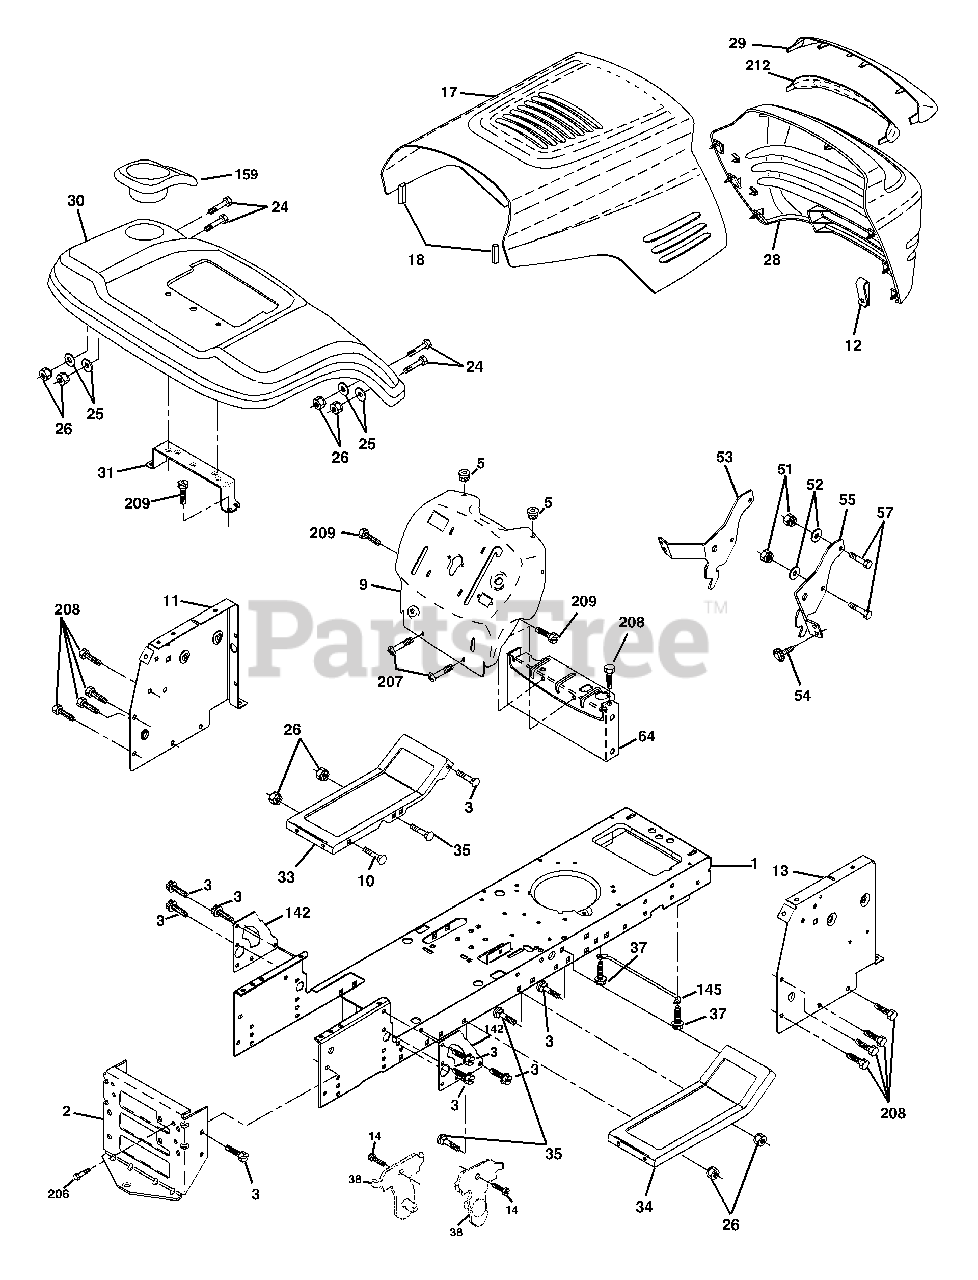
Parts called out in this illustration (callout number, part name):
1	Chassis
2	Drawbar
3	Screw 3/8-16x.75
5	Bumper Hood/Dash
10	Bolt Carriage 3/8-16 x 1
11	Panel Dash Lh
12	Clip Tinnerman
13	Panel Dash Rh
14	Screw Thdrol 3/8-16 x 1-1/4
17	Hood W/Side Louvers
18	Bumper Hood Large
24	Bolt Fin Hex 3/8-16 x 1 Gr 5
25	Washer 13/32 X 13/16 X 12 Ga
26	Nut Lock Hex W/Ins 3/8-16 Unc
29	Lens
30	Fender Footrest STLT Pnt
31	Bracket Support Fender
33	Footrest Pnt Lh
34	Footrest Pnt Rh
35	Bolt Rdhd Sht Sqnk 3/8-16 x 3/4
37	Screw Thdrol 6/16-18 x 1/2 TYT
38	Bracket Asm. Pivot Mower Rear
51	Nut Lock Hex W/Ins 1/4-20
52	Washer 9/32 x 7/8 x 16 Ga.
53	Bracket Grille Lh
54	Screw Hex Wshd 8-18 x 7/8
55	Bracket Grille Rh
57	Bolt Hex 1/4-20 x 3/4
64	Dash Lower STLT
142	Plate Reinforcement STLT
145	Rod Pivot Chassis/Hood
159	Cupholder
206	Bolt Shoulder 5/16-18
207	Screw Thdrol 5/16-18 x 1/2
208	Screw Thdrol 3/8-16 x 1/2
212	Insert Lens Reflect
